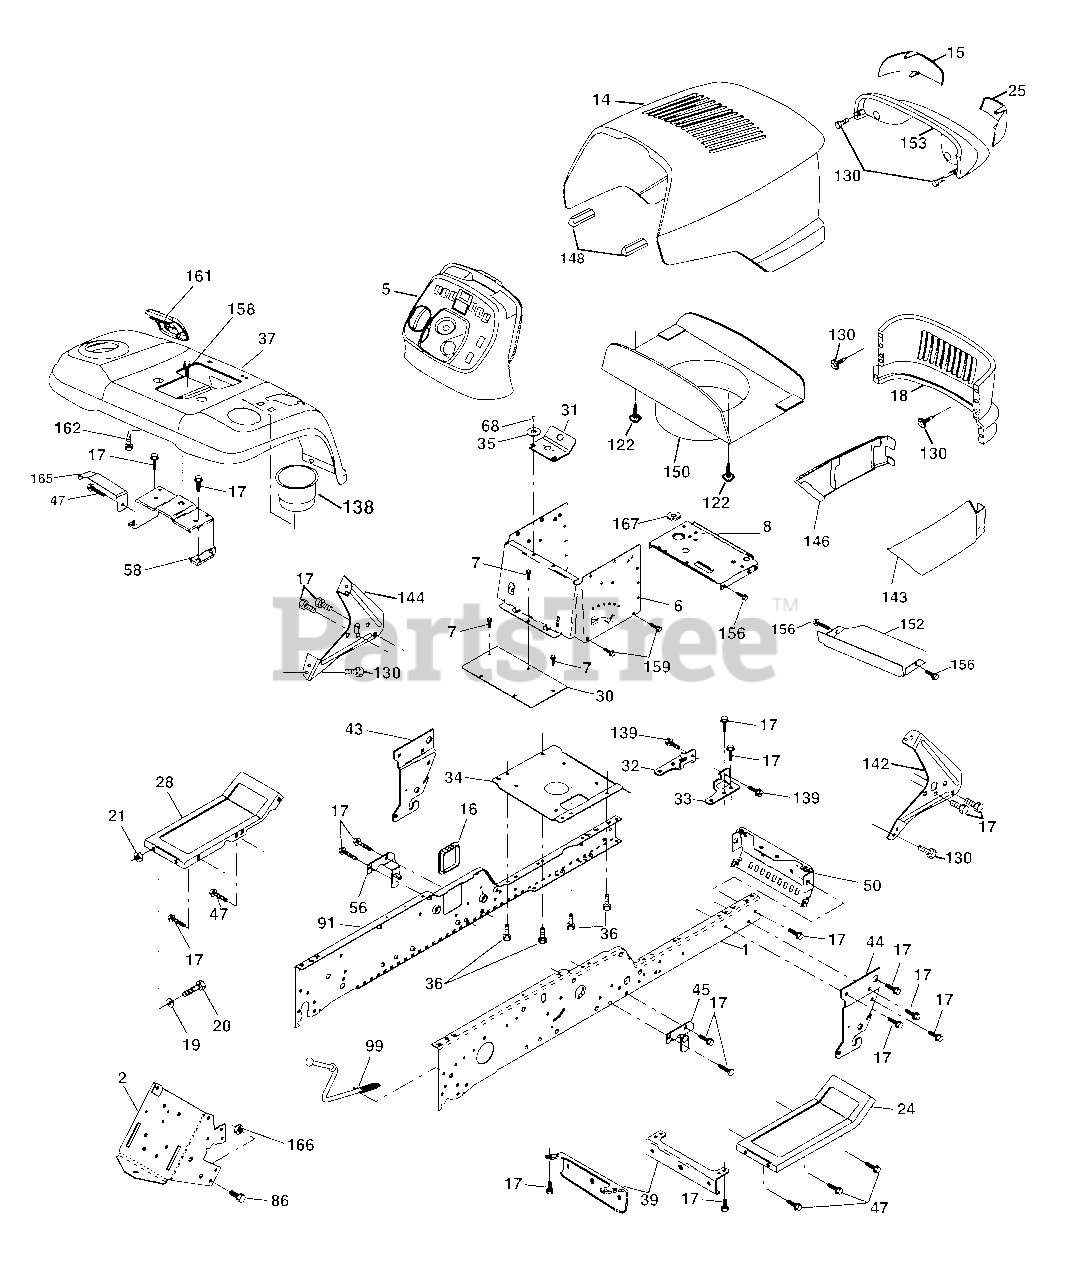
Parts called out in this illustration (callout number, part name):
1	Rail, Frame RH
2	Drawbar, Gt
5	Dash, Plastic
6	Dash, 1PCS, Lower
7	Screw, Thd Cut 1/4-20 x 1/2
8	Support, Battery
14	Hood Asm., Pnt
15	Lens LH
16	Cover, Access
17	Screw, 3/8-16 x 3/4
18	Grille
19	Washer 13/32 x 13/16 x 12 Ga.
20	Bolt, Fin Hex 3/8-16 x 1
21	Nut, Crownlock 3/8-16
24	Footrest, RH
25	Lens RH
28	Footrest, LH
31	Bracket Supt 1-pc Vgt Steering
32	Bracket, Frame Pivot Lh
33	Bracket, Frame Pivot Rh
34	Plate Asm Engine Chassis
35	Washer 11/32 x 11/16 x 16 Ga.
36	Screw 5/16-18 x 3/4
37	Fender, Pnt.
39	Bracket, Axle Front
43	Bracket, Spnsn Front Lh
44	Bracket, Spnsn Front Rh
45	Bracket Asm., Susp Chassis Rh
47	Screw Thdrol 3/8-16 x 1/2
50	Bracket, Chassis Front
56	Bracket Asm., Susp Chassis Lh
58	Bracket Asm., Fender
68	Screw, 5/16-18 x 1/2
86	Bolt, Fin Hex 7/16-14 Unc x 1-1/4
91	Rail, Frame Lh
99	Rod Asm. Bypass
122	Screw Hex WSHD 8-18 x 7/8
130	Screw Hw Hd Hi-Lo #13-16 x 3/4
138	Cupholder
139	Bolt Shoulder 5/16-18
142	Bracket Dash Stealth RH
143	Skirt Grille RH
144	Bracket Dash Stealth LH
146	Skirt Grille LH
148	Extrusion Bumper
150	Duct Heat Hood
152	Shield, Browning
153	Light Box Asm. w/Lens
156	Screw 5/16-18 x 3/4
158	Screw 3/8-16 x 1/2
159	Screw 3/8-16 x 3/4
161	Console Fuel Window
162	Screw Hex 1/4-1/2 Unc
165	Bracket Support Tank
166	Nut, Crown Lock 7/16-14 Unc
167	Bushing Snap
